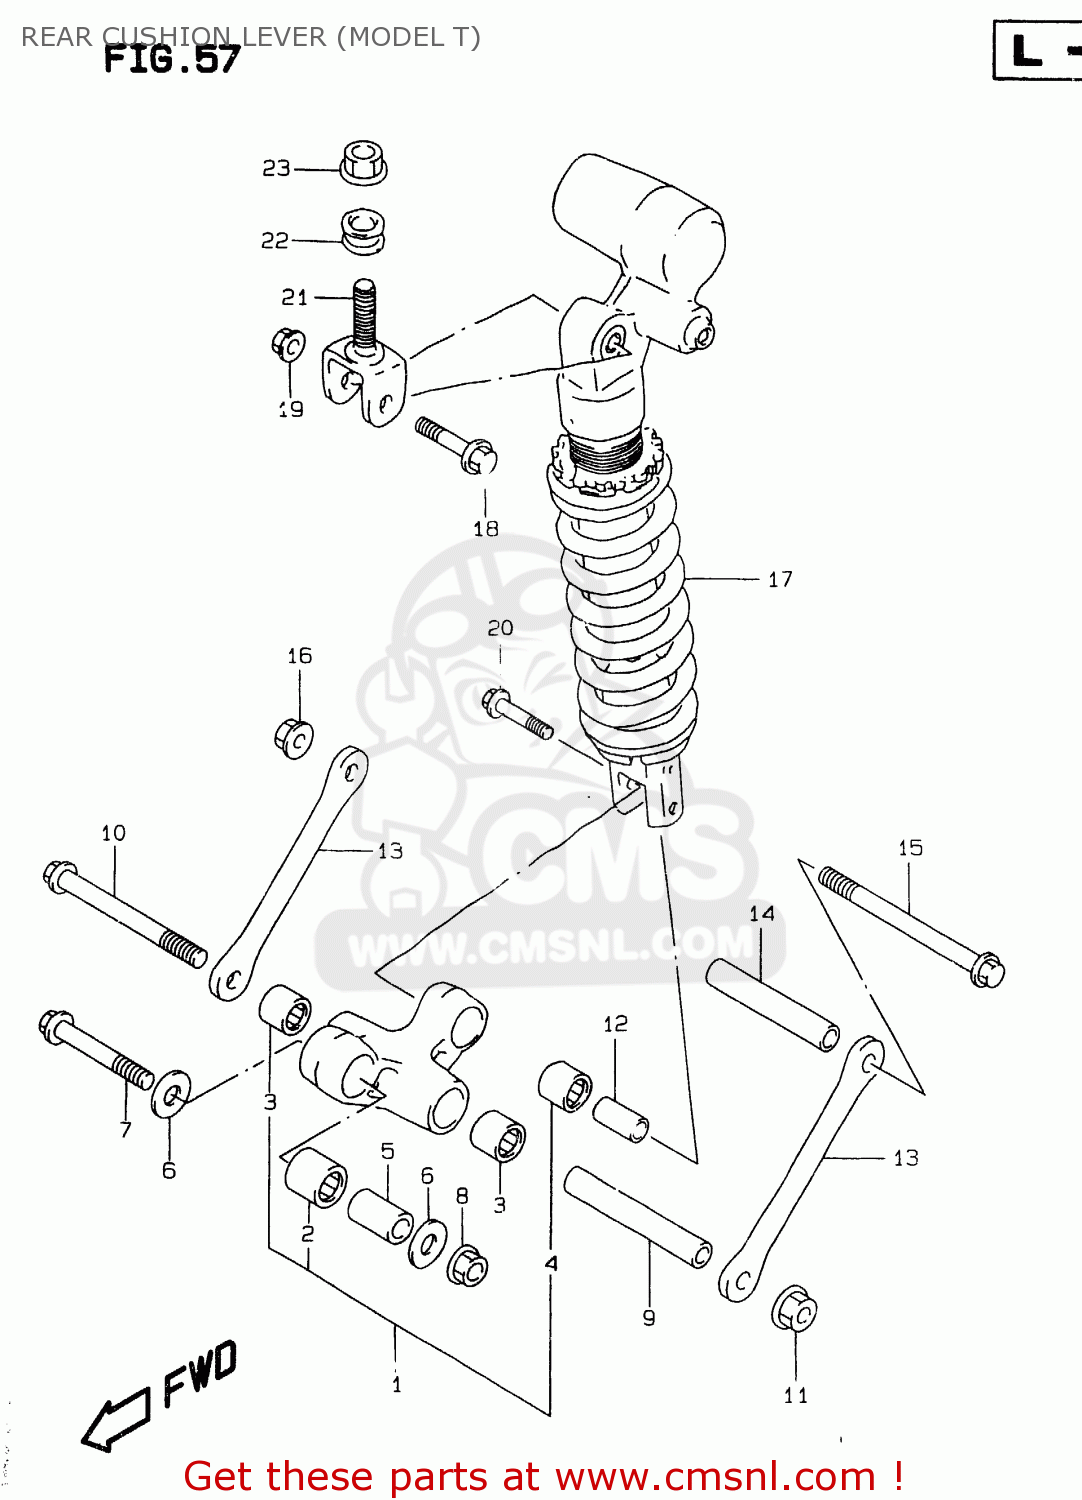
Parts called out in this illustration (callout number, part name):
1	LEVER SET,RR CUSHION
2	BEARING(20X27X30)
3	BEARING(17X24X20)
4	BEARING(17X24X26)
5	SPACER,RR CUSHION LEVER FR
6	WASHER
7	BOLT,RR CUSHION LEVER FR
8	NUT 12MM
9	SPACER,RR CUSHION LEVER CTR
10	BOLT,RR CUSHION LEVER CTR
11	NUT 12MM
12	SPACER,RR CUSHION LEVER
13	ROD,RR CUSHION LEVER
14	SPACER,RR CUSHION LEVER CTR
15	BOLT,RR CUSHION LEVER CTR
16	NUT 12MM
17	ABSORBER ASSY,RR SHOCK
18	BOLT(10X54)
19	NUT
20	BOLT(10X44)
21	BRACKET,RR SHOCK ABSORBER UPR
22	SPACER,RR SHK ABS BRACKET
23	NUT
